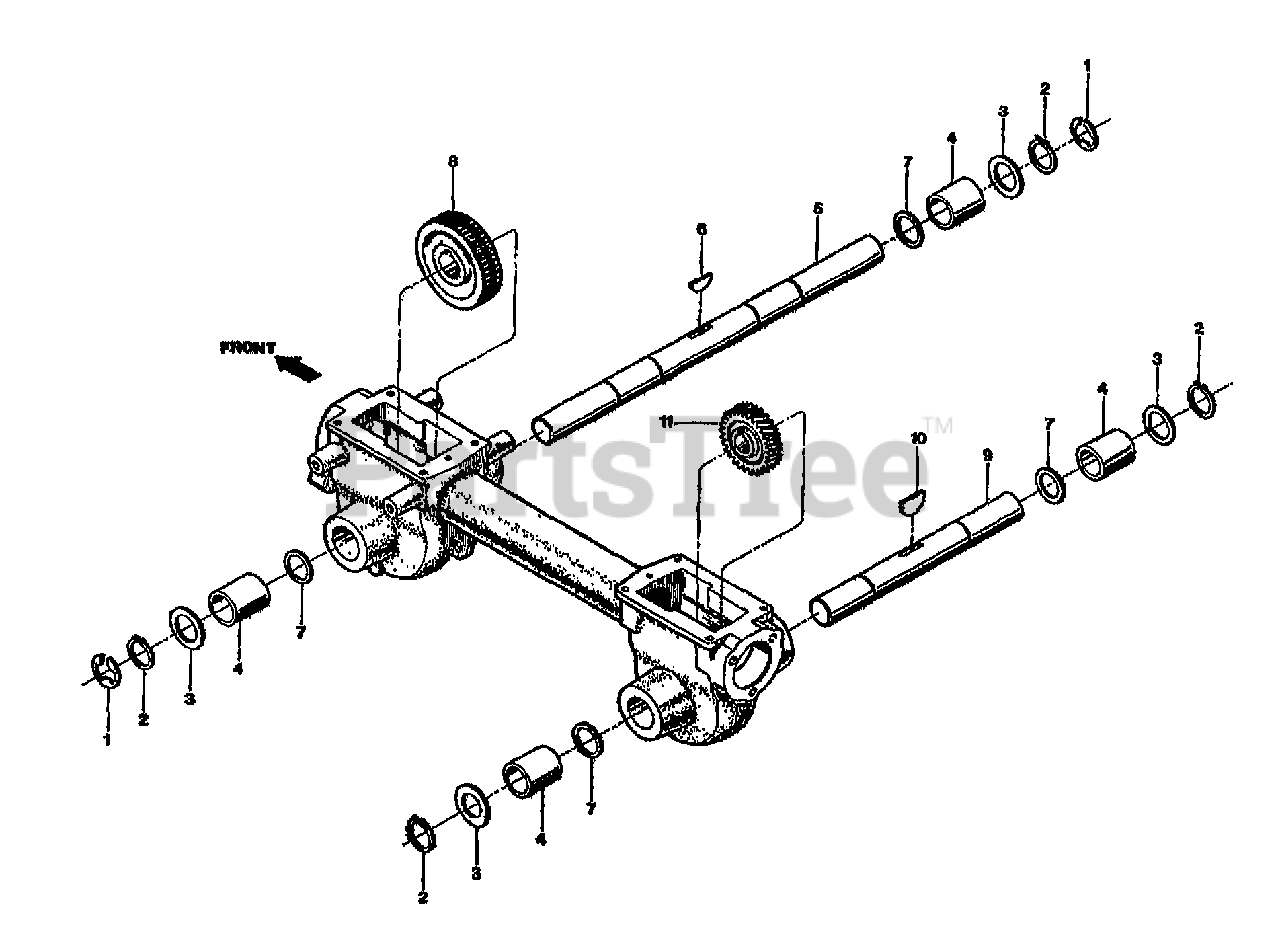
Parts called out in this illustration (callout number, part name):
1	RING-RETAINING 5133-989
2	RING-HEAVY EXT .906 ID
3	SHIM-1.375X1.015X.062
3	SHIM-1.375X1.015X.03
3	SHIM-1.375X1.015X.015
3	SHIM-1.375X1.015X.01
3	SHIM-1.375X1.015X.005
4	BUSHING-1.25X1.005X1.5
5	SHAFT-WHEEL MACH
6	KEY-HI PRO .25X1.062
7	SHIM-1.234X1.015X.062
8	GEAR-WORM 61 TEETH MACH
9	SHAFT-TILLER MACH
10	KEY-WOODRUFF .25X1.12
11	GEAR-WORM BRONZE MACH
